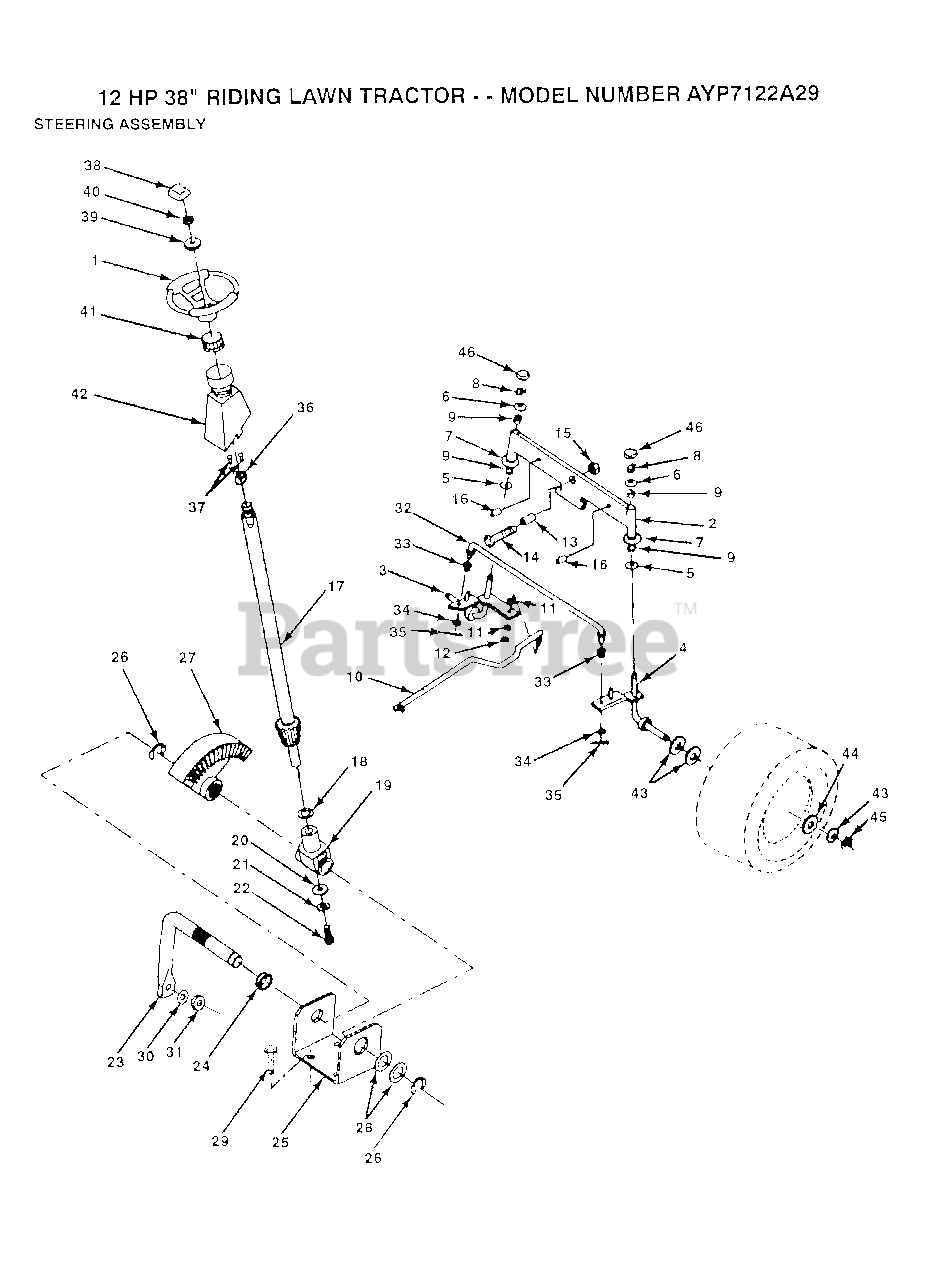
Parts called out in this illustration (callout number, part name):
4	SPINDLE ASM RH
5	WASHER .T
6	WASHER
7	WASHER
8	RING
9	COL. SRTG. BEAR.
11	LOCKWASHER
13	BEARING
14	BOLT HEX 5/8-11
16	AXLE PIN
17	SHAFT ASM
18	THRUST WASHER
19	SUPPORT.SHAFT
21	LOCKWASHER
22	"SCREW,SPECIAL"
24	NYLINER T
25	"BRKT,STEERING"
26	RING
28	WASHER .T
29	SCREW
30	LOCKWASHER
32	TIE ROD
34	WASHER
35	COTTER PIN
38	INSERT-WHEEL LT
39	WASHER T
40	GRIPCO NUT
41	ADAPTER-WHEEL LT
42	"TUBE, STR SHAFT"
43	WASHER
44	WASHER
45	RING
46	CAP
